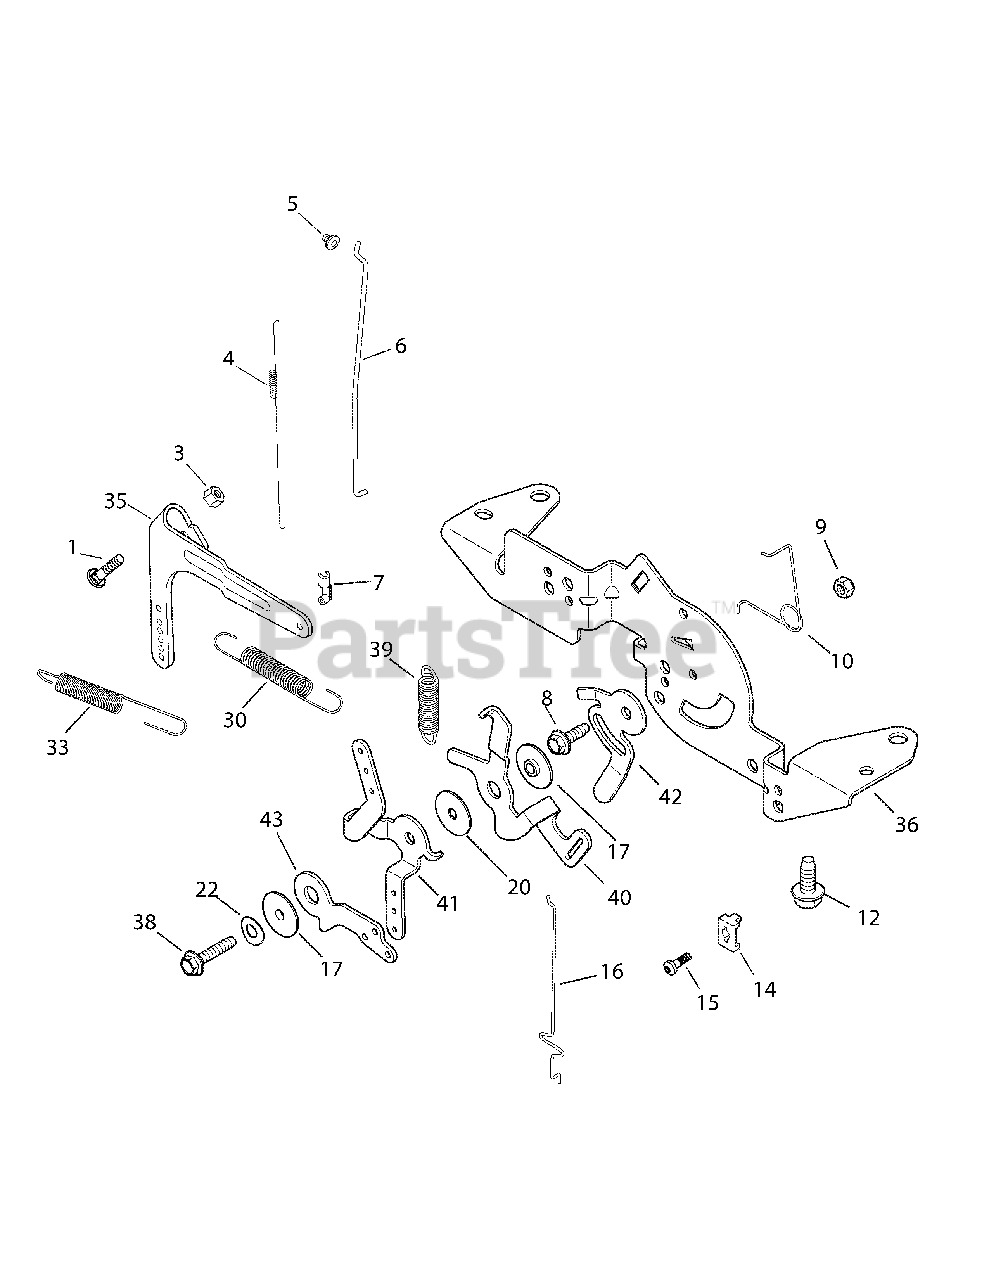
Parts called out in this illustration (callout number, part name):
1	Rd. Hd. Sq. Neck Bolt, M6 X 1.0 X 25
3	Flg. Nut, M6 X 1.0
4	Linkage Spring
5	Linkage Retaining Bushing
6	Throttle Linkage
7	Throttle Linkage Bushing
8	Flg. Thd. Frm. Screw, M5 X 0.8 X 16
9	Lock Nut, M5 X .8
10	Choke Return Spring
12	Flg. Thd. Frm. Screw, M6 X 1.0 X 16
14	Cable Clamp
15	Lbd. Thd. Frm. Screw, M5 X 0.8 X 16
16	Choke Linkage
17	Control Assembly Spacer
20	Flat Washer. 5.5mm
22	Spring Washer, 1.4
30	Governor Spring
33	Governor Spring
35	Governor Lever
36	Control Bracket
38	Thd. Frm. Screw, M5 X 0.8 X 25mm
39	Speed Control Spring
40	Governor Spring Lever
41	Speed Control Lever
42	Speed Setting Lever
